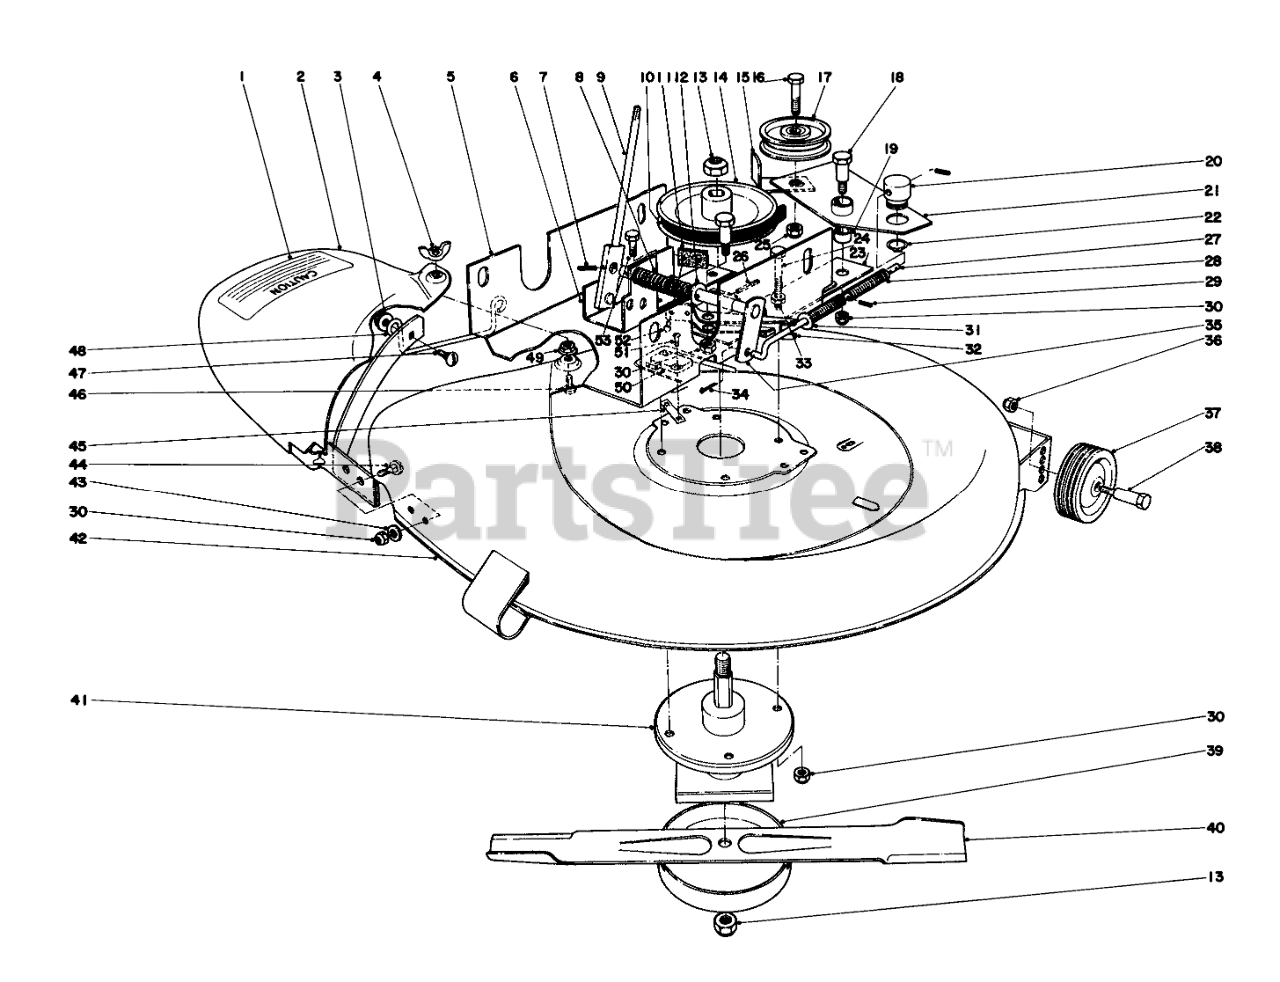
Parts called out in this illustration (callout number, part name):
1	Decal
2	DEFLECTOR WA R
3	NUT-LOCK, HHF
4	Wing Nut
5	CHANNEL HT ADJ R
6	Mounting Bracket Blade
7	PIN-SPRING
8	COMP SPRING O
9	Deck Engagement Lever
10	V-Belt
11	BLADE BRAKE LINING
12	WASHER-FLAT
14	Pulley
15	Belt Retainer
16	SCREW-HH
17	Flat Idler
18	CLUTCH PIVOT BOLT
19	BUSHING
20	Pivot Pin
21	Idler Arm (Incl. Ref. #19)
22	RING-RETAINING
23	Bracket Idler Mounting
24	SCREW-HH
25	NUT-LOCK, CONE
26	Pin-Roll
27	Blade Engage Rod
28	DECK IDLER SPRING
29	PIN-SPRING
30	NUT-LOCK, CONE
31	WASHER
32	Blade Brake
33	NUT-JAM
34	PIN-COTTER
35	Linkage
36	Nut
37	Wheel
39	Cup
40	Blade
41	Mower Spindle
42	HOUSING WA R
43	WASHER-FLAT
44	BOLT-CARR
45	NUT-SPEED
46	BOLT-CARR
47	SCREW-CARRIAGE
48	Bracket Foot Guard
49	PAL NUT
50	MICRO SWITCH
51	SCREW-SPH
52	Rivet
53	SCREW-HH
